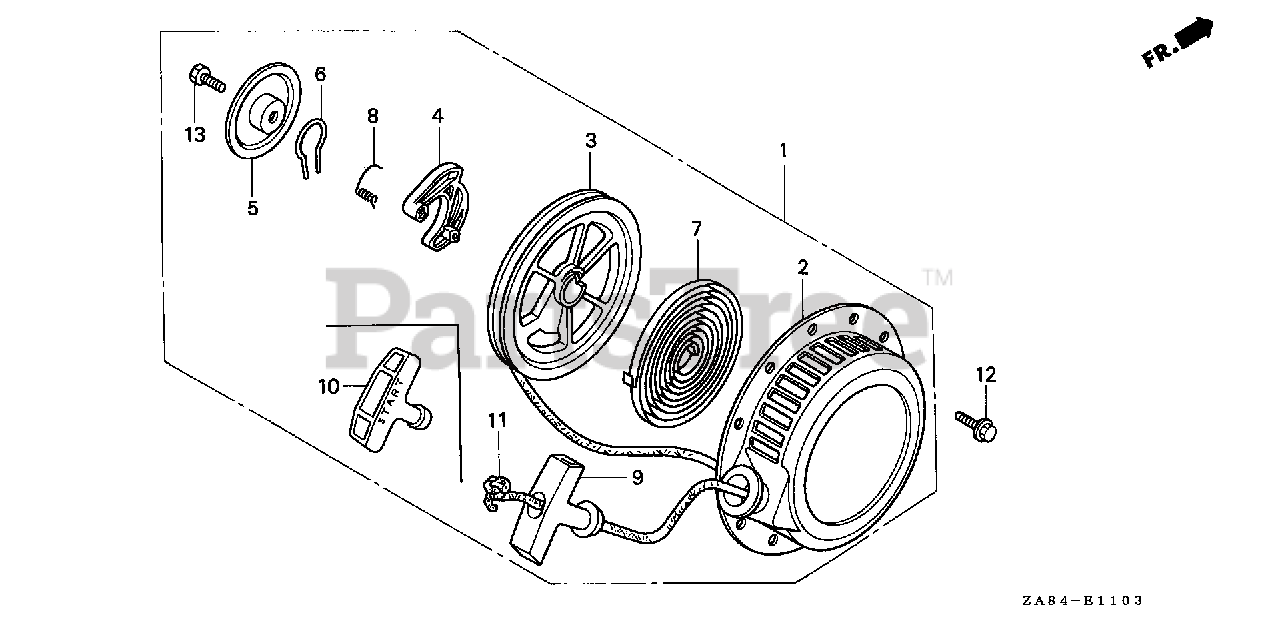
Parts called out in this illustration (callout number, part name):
1	STARTER ASSY., RECOIL *R8* (BRIGHT RED)
1	STARTER ASSY., RECOIL *R280* (POWER RED)
2	CASE, RECOIL STARTER *R8* (BRIGHT RED)
3	REEL, RECOIL STARTER
4	RATCHET, STARTER
5	PLATE, FRICTION
6	SPRING, FRICTION
7	SPRING, RECOIL STARTER
8	SPRING, RETURN
9	KNOB, STARTER
10	KNOB, RECOIL STARTER
11	ROPE, RECOIL STARTER (#4X65") (N/A: USE P/N 08540-ZG921-11)
12	BOLT, FLANGE (6X8)
13	BOLT, HEX. (6X20)
